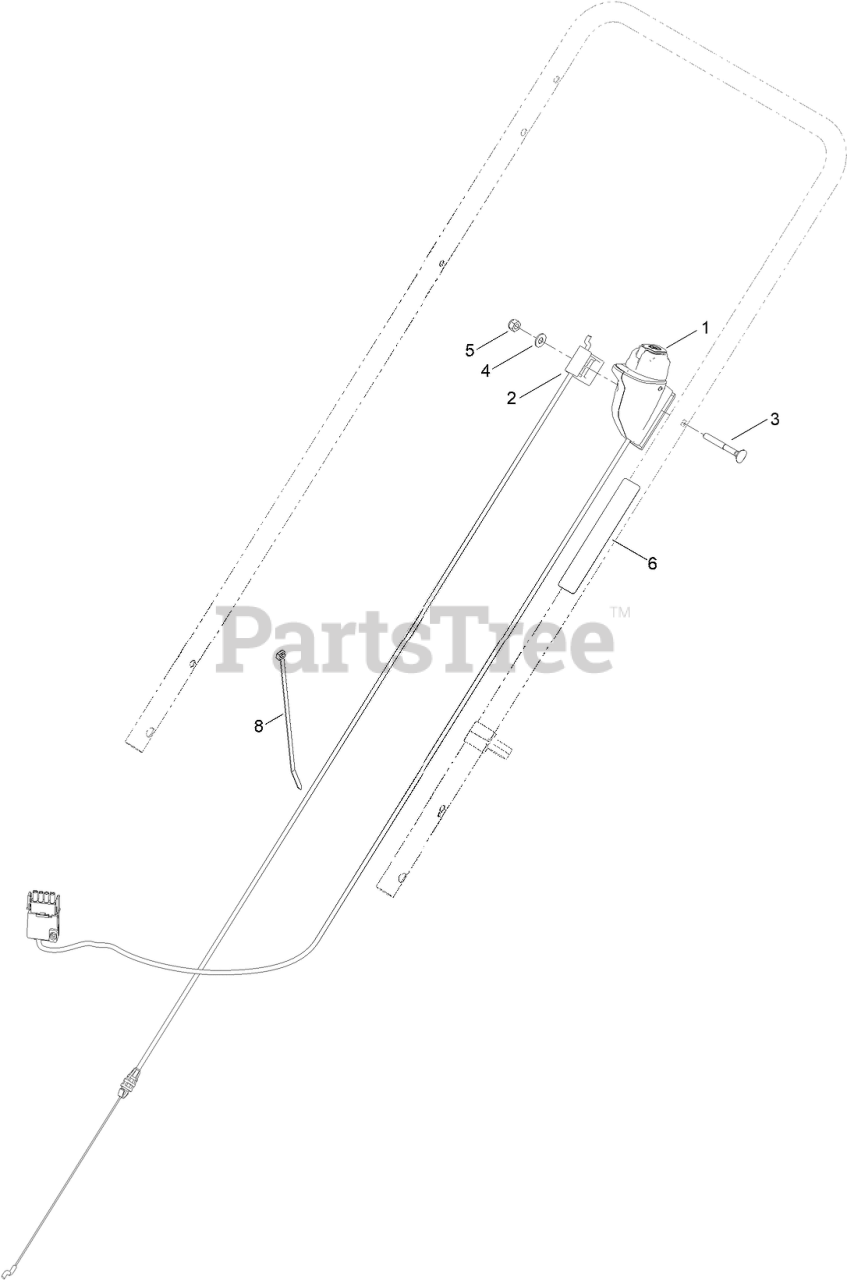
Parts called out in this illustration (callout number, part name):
1	STARTER SWITCH ASM
2	CABLE - BRAKE
3	SCREW-HANDLE
4	WASHER-FLAT
5	NUT-LOCK, NI
6	DECAL-CONTROLS (60V START)
8	TIE-CABLE
